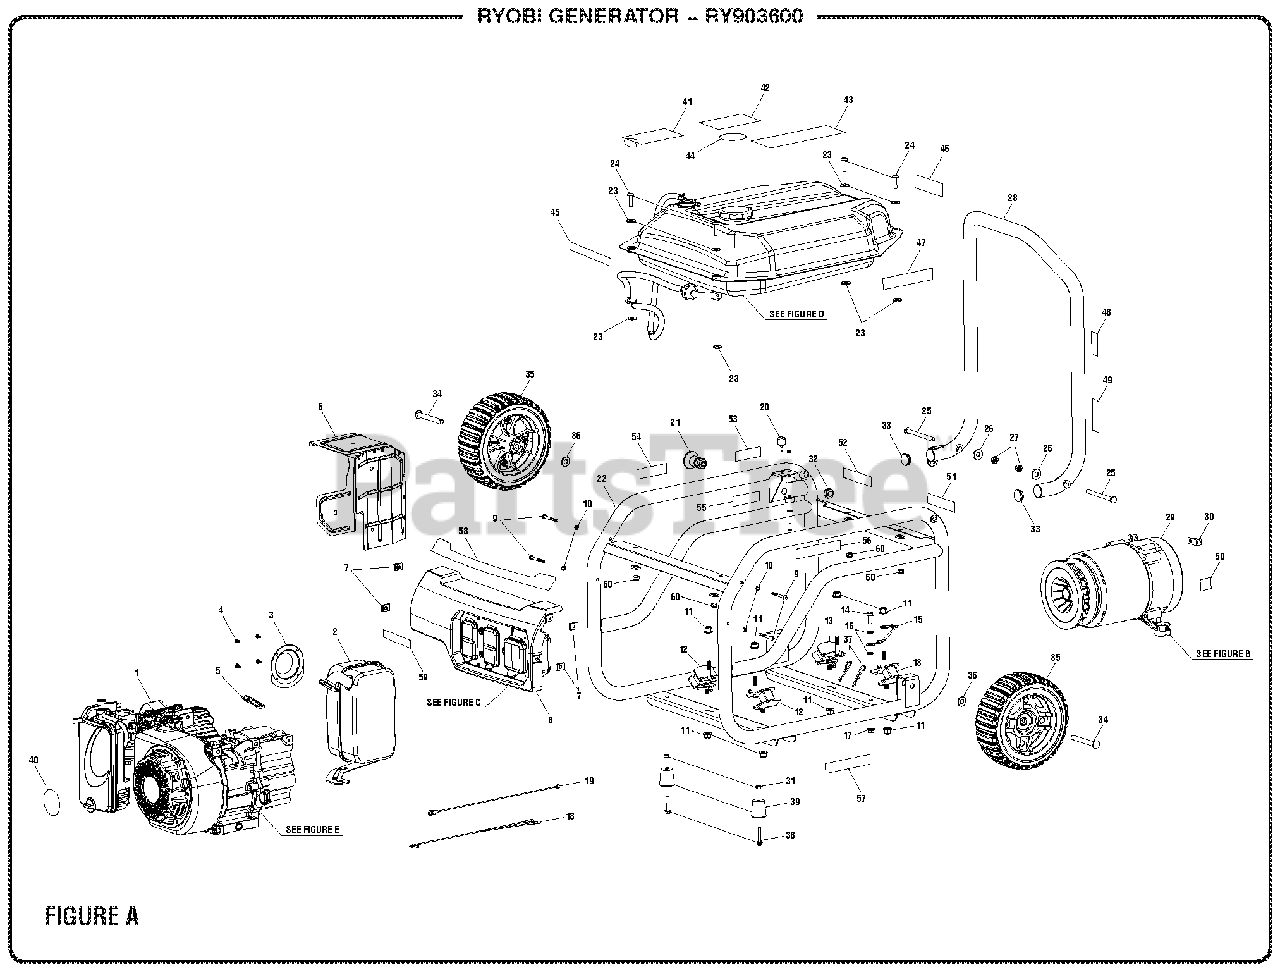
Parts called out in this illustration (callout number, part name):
3	Spark Arrester
4	Screw (8-32 x 3/8 in.)
5	Exhaust Gasket
6	Heat Shield
7	U-Clip (M6)
8	Control Panel Assembly
9	Screw (M5 x 35 mm)
10	Washer (ID5.3 x OD10 x 0.5t)
11	Lock Nut (M8)
12	Isolator (Right)
13	Isolator (Left)
14	Bolt (5/16-18 X 0.75 in.)
15	Ground Wire Assembly
16	Star Washer (5/16 in.)
17	Flange Nut (5/16-18)
18	Wire Assembly (Black)
19	Wire Assembly (Green)
20	Handle Bumper
21	Handle Release Pin
22	Carrier Assembly
23	Washer (1/4 in., Type A)
24	Screw (1/4-20 x 1 in., T30 Torx Hd.)
25	Handle Pivot Bolt
26	Washer (5/16 in.)
27	Lock Nut (5/16-18)
29	Generator Head Assembly
30	Ground Lug
31	Lock Nut (M8)
32	Lock Nut (1/2-20)
34	Axle Bolt
36	Washer (M10)
37	Hitch Pin
38	Bolt (M8 x 45 mm, Hex Flange Hd.)
40	Recoil Label
41	Notice Hangtag
42	Warning Label
43	CPSC Label
44	Fuel Stabilizer Label
45	Logo Label
46	Combustion Warning Label
47	Start Label
48	Fuel Stabilizer Label (SP/FR)
49	E85 Label
50	Ground Label
51	Ground Warning Label
52	Fire Danger Label
53	Pin Release Label
54	Inquiries Label
55	Hot Surface Label
56	Fire Distance Label
57	Lubricant Label
58	Performance Label
59	Choke Label
60	Lock Nut (1/4-20)
